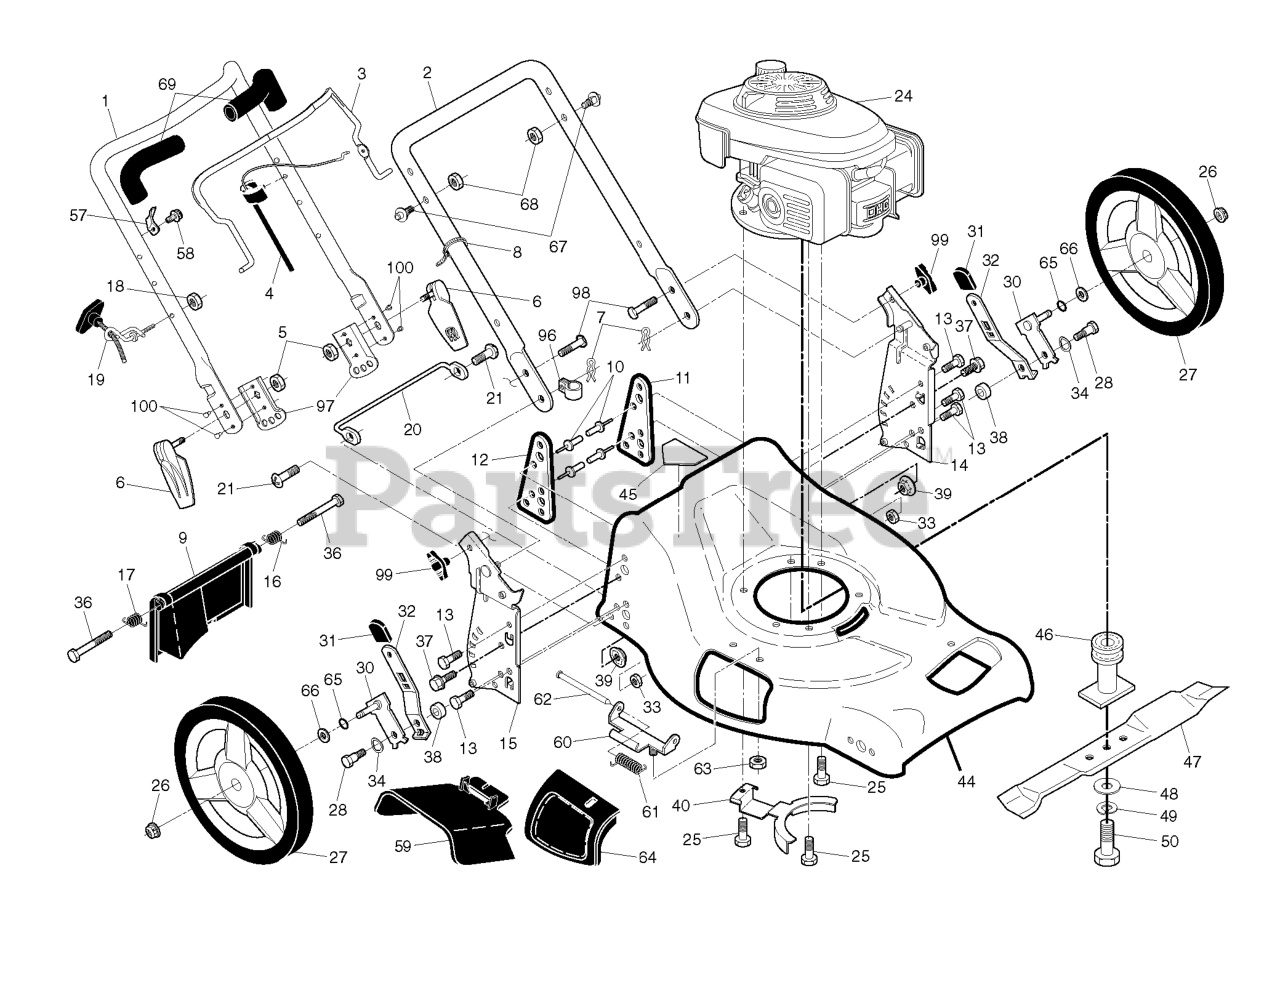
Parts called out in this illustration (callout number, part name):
1	HANDLE.ASM.UP.W/ADJ.BKT.21FGD
2	HANDLE.LOWER.21.NB.GREY
3	BAIL.CONTROL.MZR.BS.ORANGE
4	CABLE.ASM.ZONE.CONTROL
5	NUT.LOCK.5/16-18
6	QUICK.ASM.RELEASE.BLACK
7	HAIRPIN COTTER
8	TIE GUIDE
9	REAR DOOR ASSEMBLY
10	RIVET BLIND
11	SUPPORT BRACKET LH
12	BRACKET.SUPRT.RH.21.FWGD
13	SCREW 14-20 X 5/8
14	BRACKET.ASM.HDL.LT.21FGD.HW.OR
15	BRACKET.ASM.HDL.RT.21FGD.HW.N
16	SPRING.REAR.DOOR.EZ.21.LT
17	SPRING.REAR.DOOR.EZ.21.RT
18	NUT
19	RB GUIDE.ROPE.STD.BLK.ZIN WSL
20	FOOT.GUARD.21.DOM/FGD.CE.10
21	SCREW
25	BOLT 3/8-16X1-1/8
26	NUT.HEX.FLANGE.3/8-16.LOCKNUT
27	WHEEL ASSY
28	SHOULDER BOLT 5/16-18
30	ARM.ASM.AXLE.REAR.5/9.POS.BZP
31	SELECTOR KNOB
32	SELECTOR SPRING
33	NUT.71038.31-18.HEX.NYLOCK
34	WASHER.CURVED.CYLINDRICAL
37	BOLT.FIN.HEX.5/16-18X3/4
38	SPACER.HEIGHT.ADJUSTER
39	NUT.FLANGE.5/16
40	BRACKET.ENG/BELTKEEPER
44	KIT.HSG.21.FGD.MC.ORG.CE SYM
45	DECAL.INTERNATIONL.CUTFINGER
46	RB ADAPTER.BLADE.25MM.VS.LOW
47	BLADE.21.PUSH
48	WASHER,HARDEN
49	LOCKWASHER
50	SCREW, HEX HD 3/8-24 X 1-3/8
57	BRACKET.UPSTOP.RT
59	DEFLECTOR.CLIPPIN.21.FGD
60	BRACKET.ASM.HINGE.21.FWGD.
61	SPRING.TORSION
62	ROD.HINGE.21
63	LOCKNUT.NYLOC.1/4-20
64	DOOR.MULCH.21.REAR.FWGD
65	O-RING..070X.487.NEOPRENE
66	WASHER.FLAT.1/2
67	STUD.QUICK.ADJUST
68	NUT.LOCK.5/16-18
69	GRIP.HANDLE.FOAM.WIDE.(1 SIDE)
96	CLIP.CABLE.BLK
97	BRACKET.ADJ.3POS.GREY
98	BOLT
99	KNOB, DEFLECTOR
